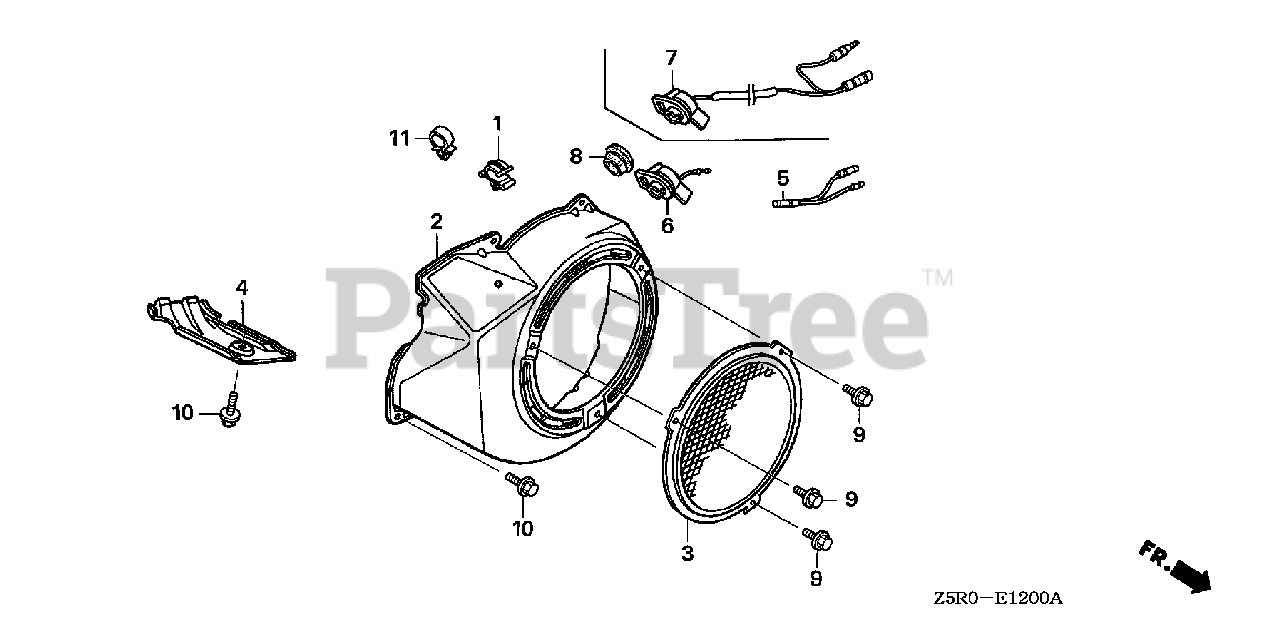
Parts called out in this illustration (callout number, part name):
2	COVER, FAN *NH1* (BLACK)
5	SUB-HARNESS
8	GROMMET, DRAIN HOLE
10	BOLT, FLANGE (6X12) (CT200)
11	CLIP, WIRE HARNESS (6MM) (WHITE)
